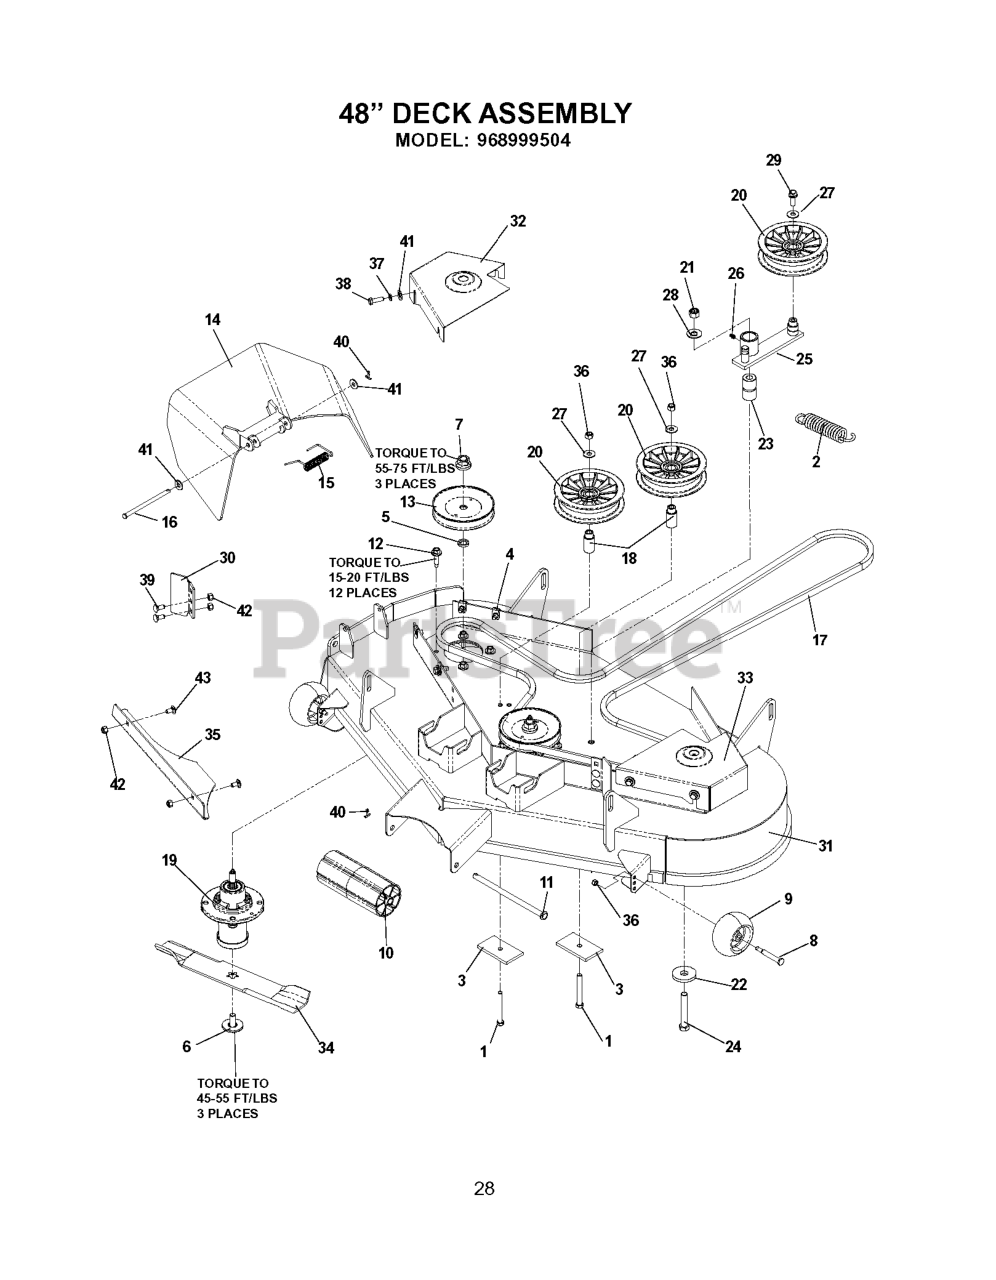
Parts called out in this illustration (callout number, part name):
1	HCS 3/8C X 3
3	SUPPORT PLATE
4	U-CLIP 5/16-18 NUT RETAINER
5	WASHER-SPACER
6	BOLT 7/16 ASM BLADE
7	LOCKNUT - 9/16
8	BOLT, SHOULDER
9	WHEEL GAGE DONUT
10	NOSE ROLLER 48"
11	NOSE ROLLER ROD
12	WASHER HEAD SCREW
13	PULLEY MANDREL
14	DISCHARGE CHUTE 48"
15	SPRING - TORSION
16	PIN-CLEVIS 5/16 DIA X 5.19 ZD
17	DECK BELT
18	IDLER BUSHING
19	MANDREL.DECK.ASSEMBLY
20	IDLER
21	NUT 1/2-13 HEX NYLOC ZD
22	WASHER, SUPPORT
23	PIVOT BUSHING
24	HCS 1/2C X 3 1/4
26	ZERK
27	WASHER 3/8 FLAT
28	WASHER 1/2 FLAT
29	4CS 3/8C X 1 SERRATED HEAD
31	DECK W/DECALS 48"
32	BELT SHIELD W/DECALS 48 RT
33	BELT SHIELD W/DECALS 48 LT
34	BLADE, 16-1/4"
35	CONFINEMENT PLATE 48" BLK
36	NUT 3/8-16 NYLOC
37	WASHER.LOCK.HVY.HLCL.SPR.5/16
38	HCS 5/16C X 1
39	BOLT 5/16C X 3/4" CARRIAGE
40	RP_COTTER PIN 1/8 X 3/4
41	WASHER 5/16 FLAT
42	NUT 5/16 NYLOC
43	CARRIAGE BOLT 5/16C X 5/8"
